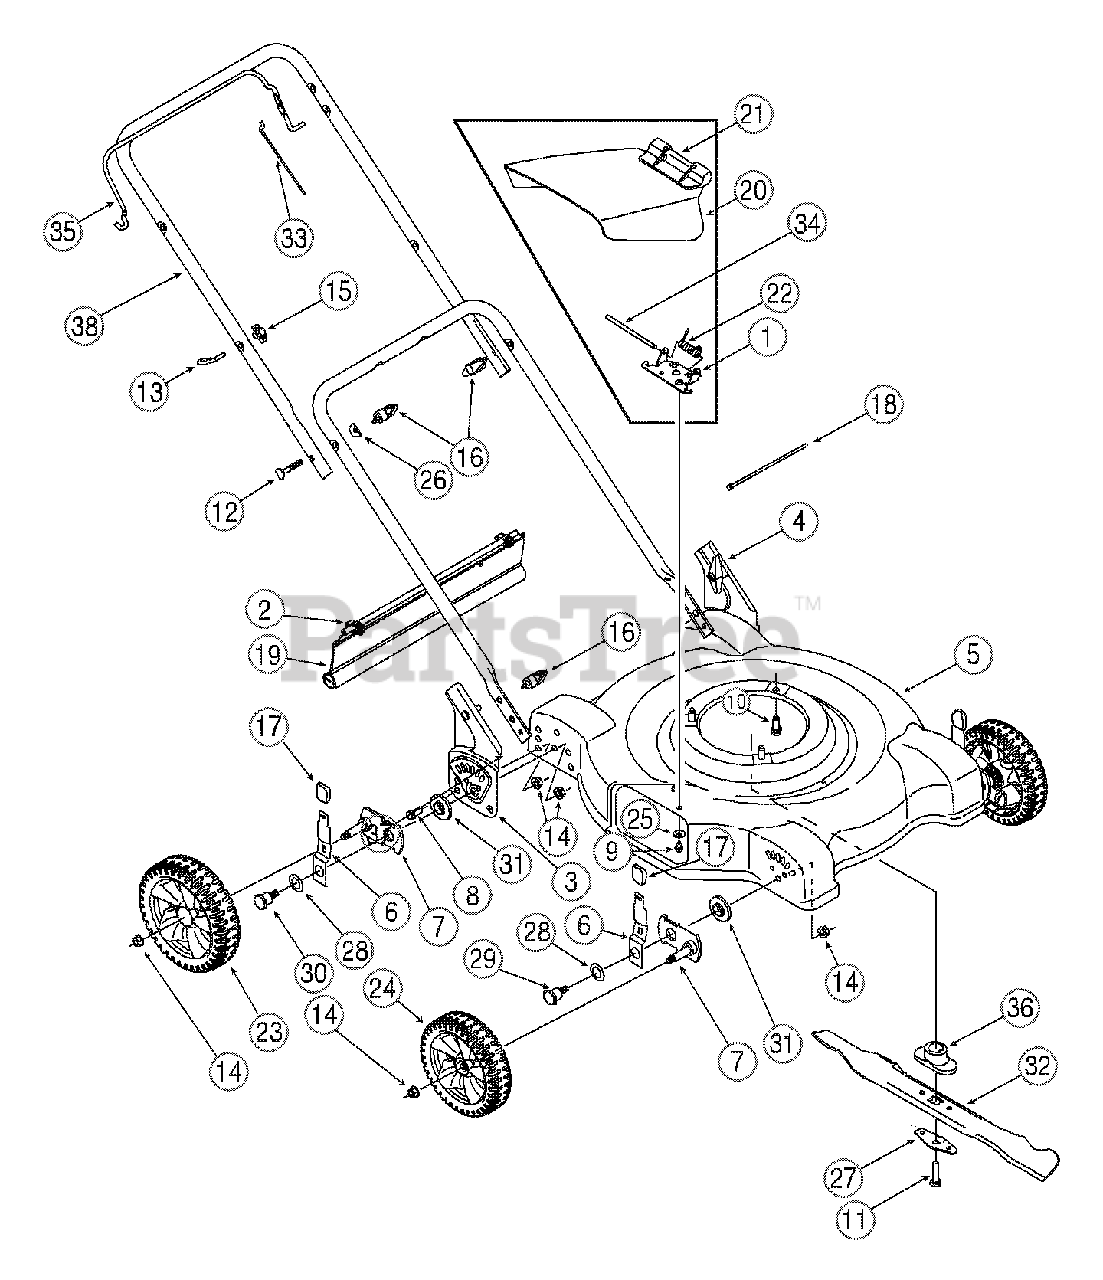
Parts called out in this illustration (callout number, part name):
1	Chute Hinge
2	Hinge Clip
6	Lever Assembly
7	Pivot Arm
8	Hex Cap Screw 3/8-16 x .75
9	TT Screw 1/4-20 x 0.5"
10	TT Screw 3/8-16 x 1.0
11	Hex Cap Screw 3/8-24 x 1.5
12	Carriage Bolt 5/16-18 x 2.0
13	Eye Bolt
14	Lock Nut 3/8-16
15	Wing Nut
16	Wing Nut
17	Height Adjuster Knob
18	Cable Tie
19	Trail Shield
20	Hinged Chute Deflector Assembly
21	Chute Deflector
22	Torsion Spring
23	Rear Wheel 8 x 1.8
24	Front Wheel 7 x 1.8
25	Bell Washer .265 ID x .75 OD
26	Saddle Washer .320 ID x .93 OD
27	Blade Bell Support
28	Bell Washer .760 ID x 1.25 OD
30	Shoulder Screw
31	Height Adjuster Bearing
32	Standard Blade 22"
33	Blade Control Cable - 37.25"
34	Hinge Pin
36	Blade Adapter
39	Shoulder Screw
